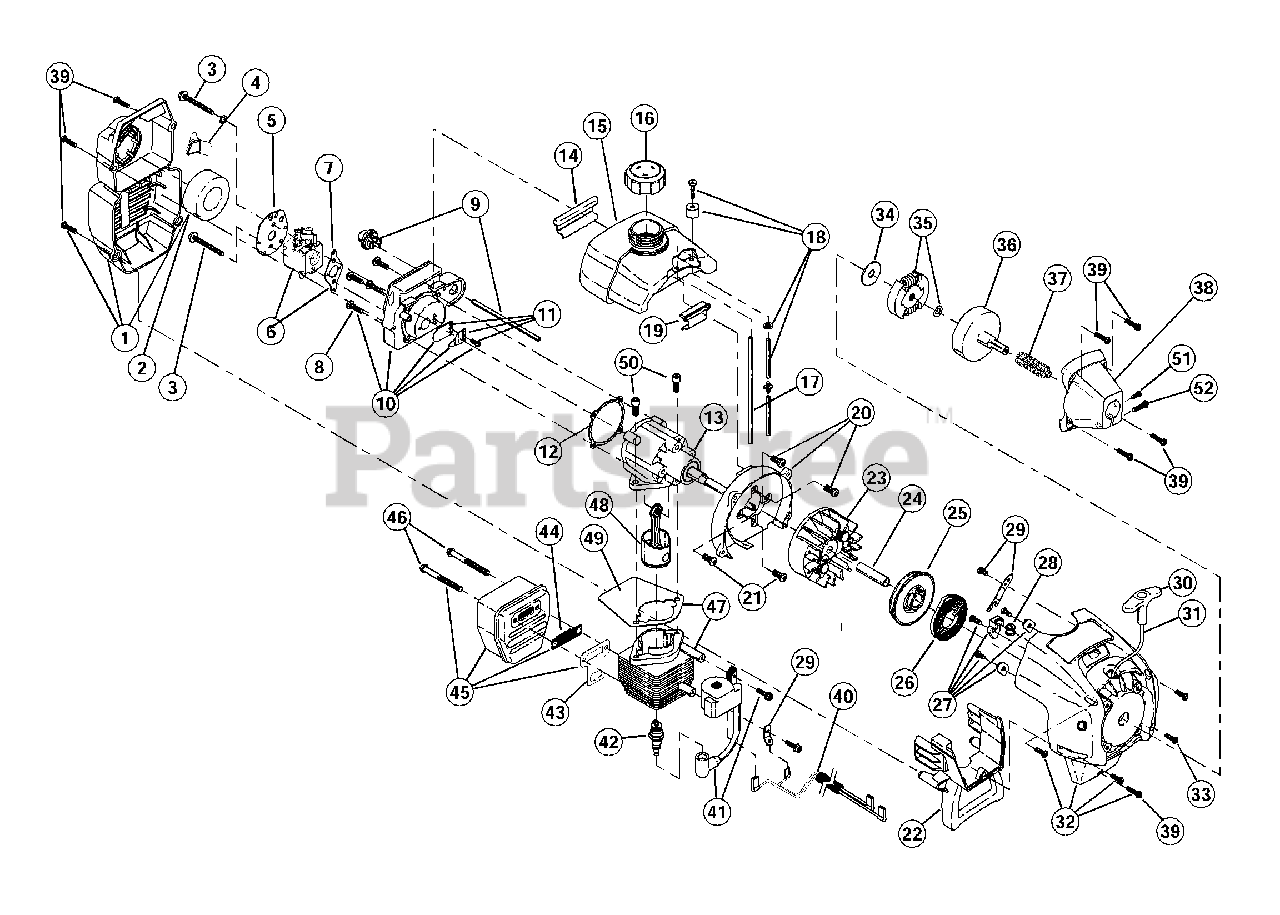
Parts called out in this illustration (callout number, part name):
1	Carburetor/Air Cleaner Cover Assembly
2	Air Cleaner Filter
3	Carburetor Mounting Screw Assembly
4	Choke Lever
5	Plate
6	Carburetor Assembly
7	Carburetor Gasket
8	Carb Mount Screw
9	Primer and Hose Assembly
10	Carb Mount Assembly
11	Reed Assembly
12	Carburetor Mount Gasket
13	Crank Case Service Assembly
14	Rear Mounting Pad
15	Fuel Tank Assembly
16	Fuel Cap Assembly
17	Fuel Return Line
18	Fuel Line Assembly
19	Front Mounting Pad
20	Shroud Assembly
21	Shroud Screw
22	Shroud Extension and Stand
23	Flywheel Assembly
25	Recoil Pulley Assembly
26	Recoil Spring
27	Pulley Retainer Assembly
28	Rope Guide
29	Ground Tab
30	Pull Handle
32	Starter Housing Assembly
33	Housing Screw
34	Clutch Washer
35	Clutch Rotor Assembly
36	Clutch Drum Assembly
38	Clutch Cover Assembly
39	Cover Screw
40	Wire Lead
41	Module Assembly
42	Spark Plug
43	Exhaust Gasket
44	Spark Arrestor
45	Muffler Assembly
46	Muffler Mounting Bolt Assembly
47	Cylinder Assembly
48	Piston and Rod Assembly
49	Cylinder Gasket
50	Cylinder Bolt
51	Anti-Rotation Screw
52	Clamping Screw
52	Ground Tab
53	Wire Cover
54	Cable Clamp
